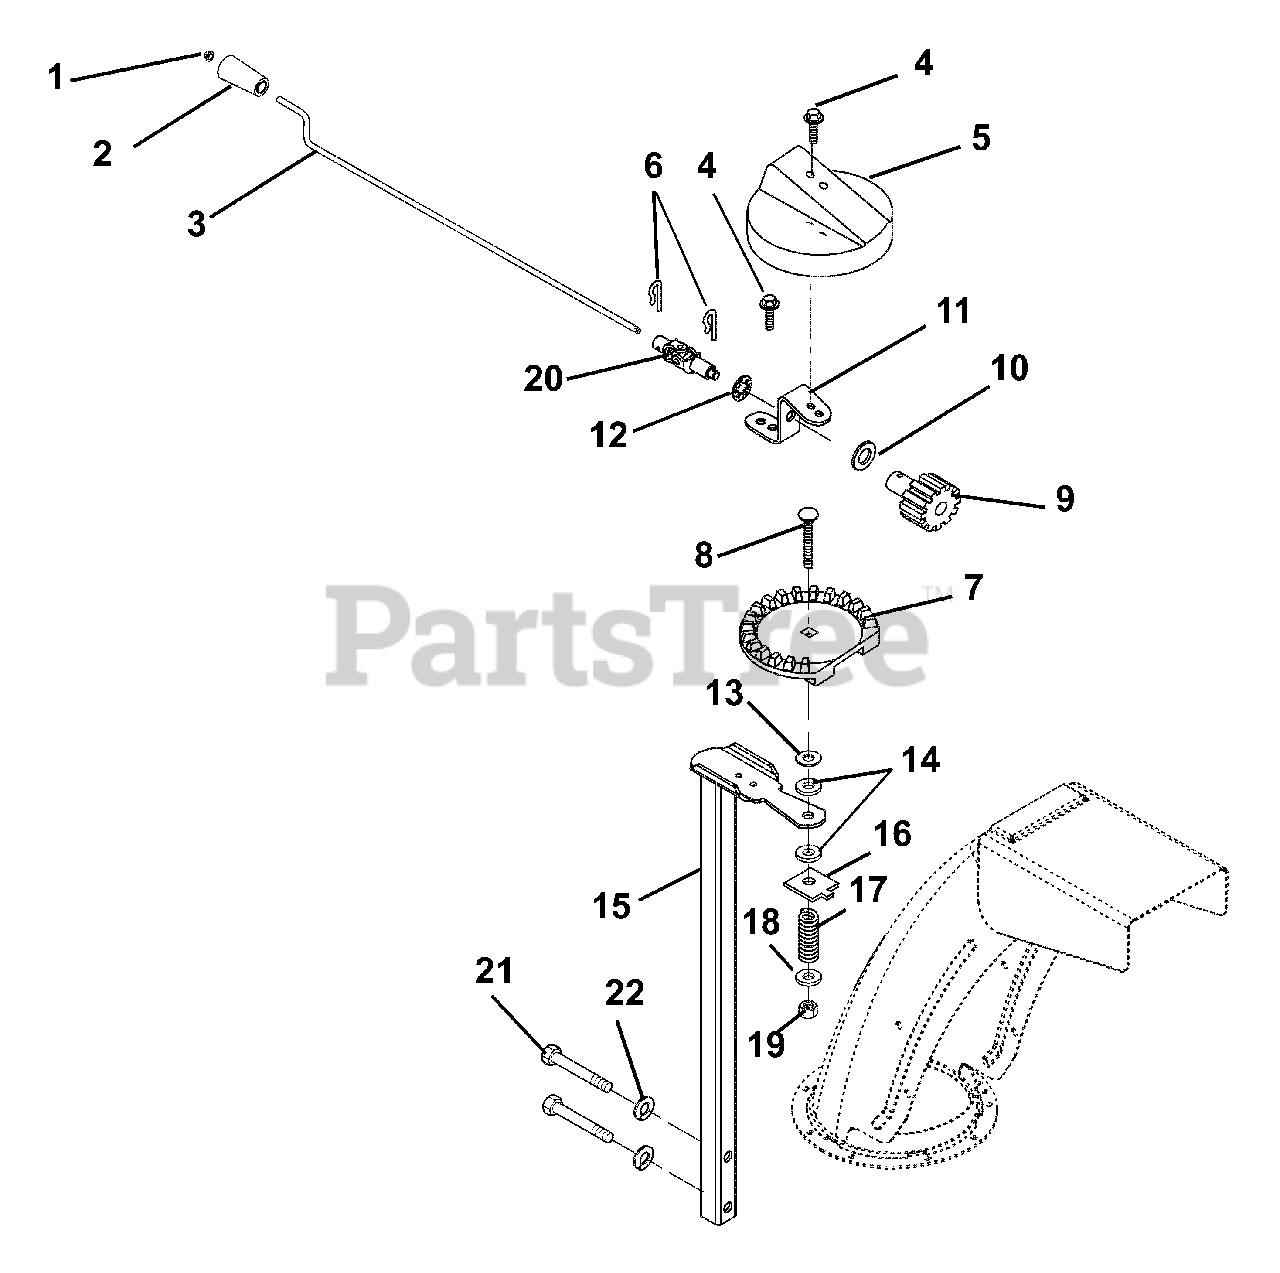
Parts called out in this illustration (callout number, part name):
1	CAP, 3/8 ROD YWZC
2	KNOB, CHUTE CRANK
3	CRANK, CHUTE
4	@SCR-TAP .25-20X.50 HWH TR YWZ
5	GEAR COVER
6	PIN, SPRING CLIP
7	CHUTE GEAR
8	@BLT-RDHDSQNK .38-16X2.50 G5YZ
9	PINION GEAR W/BRACKET
10	WSHR-FL-STL .630X1.005X.062 YZ
11	BRACKET-GEAR
12	PUSHNUT .625
13	WSHR-FL-STL .380X1.50X.062 YWZ
14	FRICTION WASHER
15	PEDESTAL, CHUTE SUPPORT
16	FRICTION PLATE
17	SG-COMP .187X.56X1.62
18	@WSHR-FL-STL.406X.812X.065 YWZ
19	@NUT-LK-CTR .38-16 YWZC
20	ASS'Y, UNIVERSAL-W/PIN END
21	@BLT-HEX .38-16X1.75 GR5 YWZC
22	@WSHR-LK .38X.094 REG YWZC
